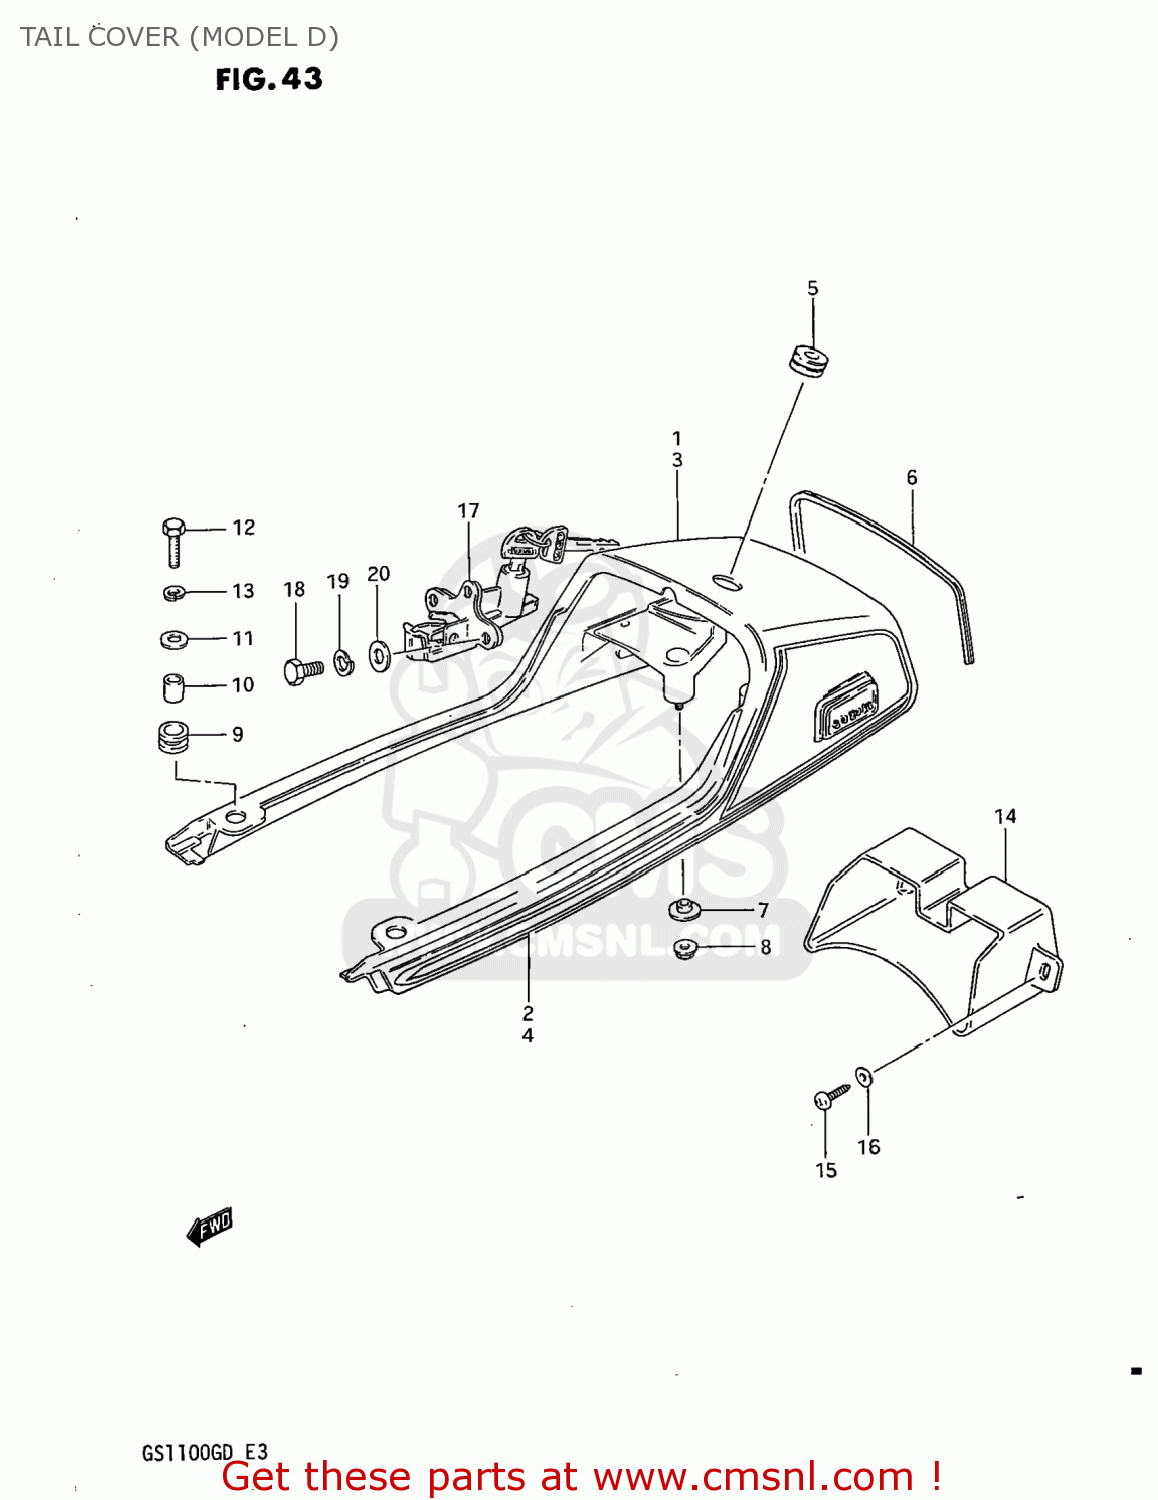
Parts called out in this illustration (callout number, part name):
1	COVER SET,SEAT TAIL
2	TAPE SET,SEAT TAIL COVER
3	COVER SET,SEAT TAIL
4	TAPE SET TAIL COVER
5	GROMMET,SEAT LOCK HOLE
6	MOLDING,SEAT TAIL COVER
7	WASHER
8	NUT 6MM
9	CUSHION
10	SPACER (7X10X12)
11	WASHER (6.5X24X1.6)
12	BOLT
13	LOCK WASHER
14	BOX, SEAT TAIL
15	SCREW
16	LOCK WASHER
17	LOCK SET,SEAT
18	BOLT
19	LOCK WASHER
20	WASHER
